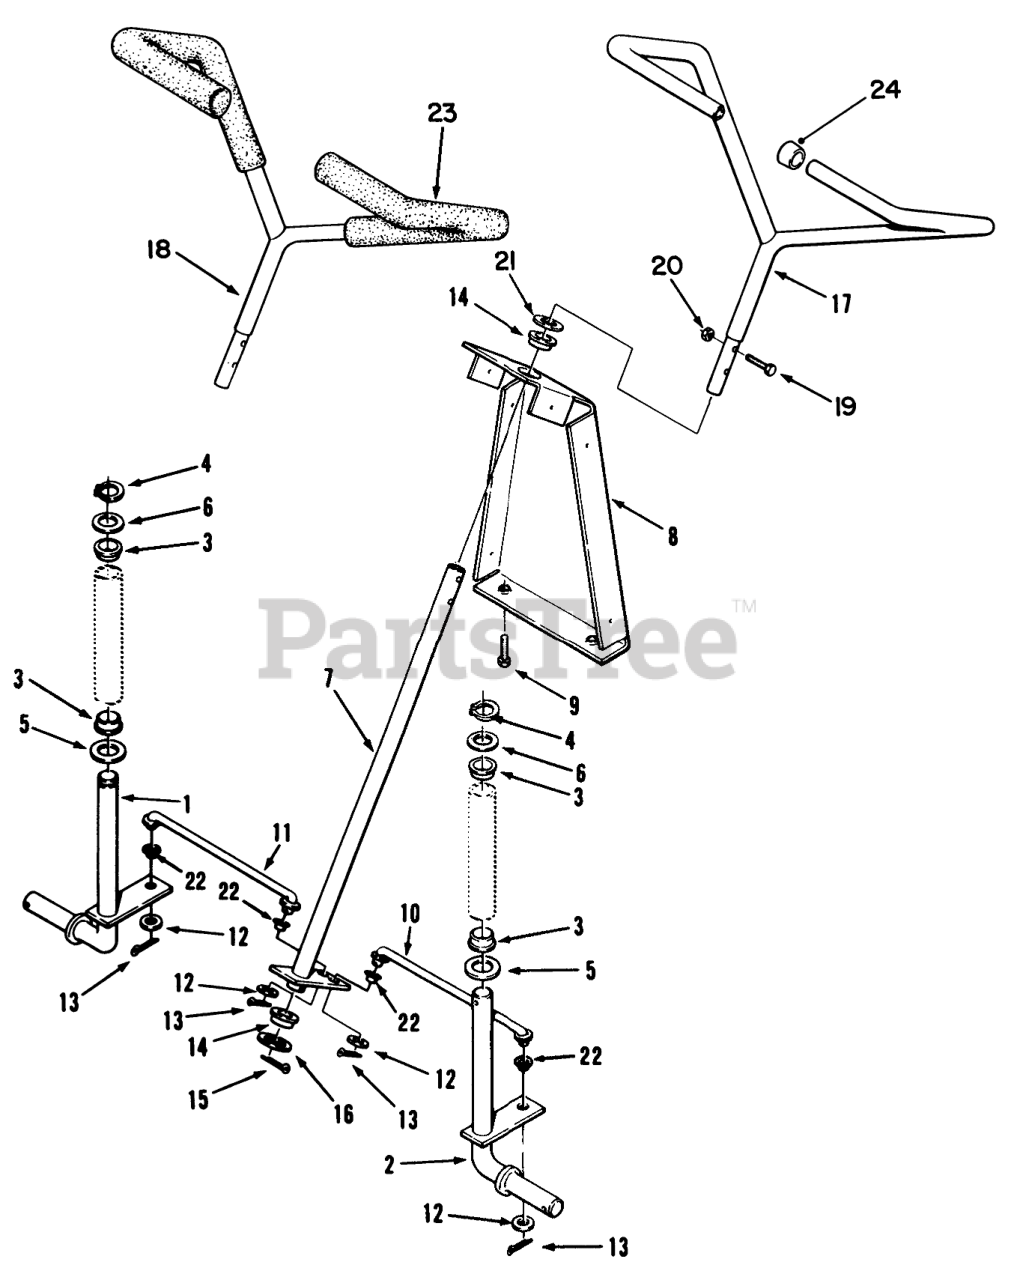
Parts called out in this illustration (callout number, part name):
1	ASS'Y-SPINDLE RH. R
2	FRONT SPINDLE ASSY LH R
3	BUSHING
4	RING-RETAINING
5	WASHER-FLAT
6	WASHER
7	ASSY STEERING SHA R
8	SUPPORT-STG UPPER B
9	HEX WASH HD SCREW
10	TIE ROD LH R
11	TIE ROD RH R
12	WASHER 25/64X5/8X.03
13	PIN-COTTER
14	BEARING
15	PIN-COTTER
16	WASHER-FLAT
17	ASSY STEERING WHEEL
18	STEERING WHEEL
19	SCREW-HH
20	NUT-LOCK, NI
21	Washer
22	BEARING
23	Grips-Steering Wheel 112-6
24	PLUG BUTTON
